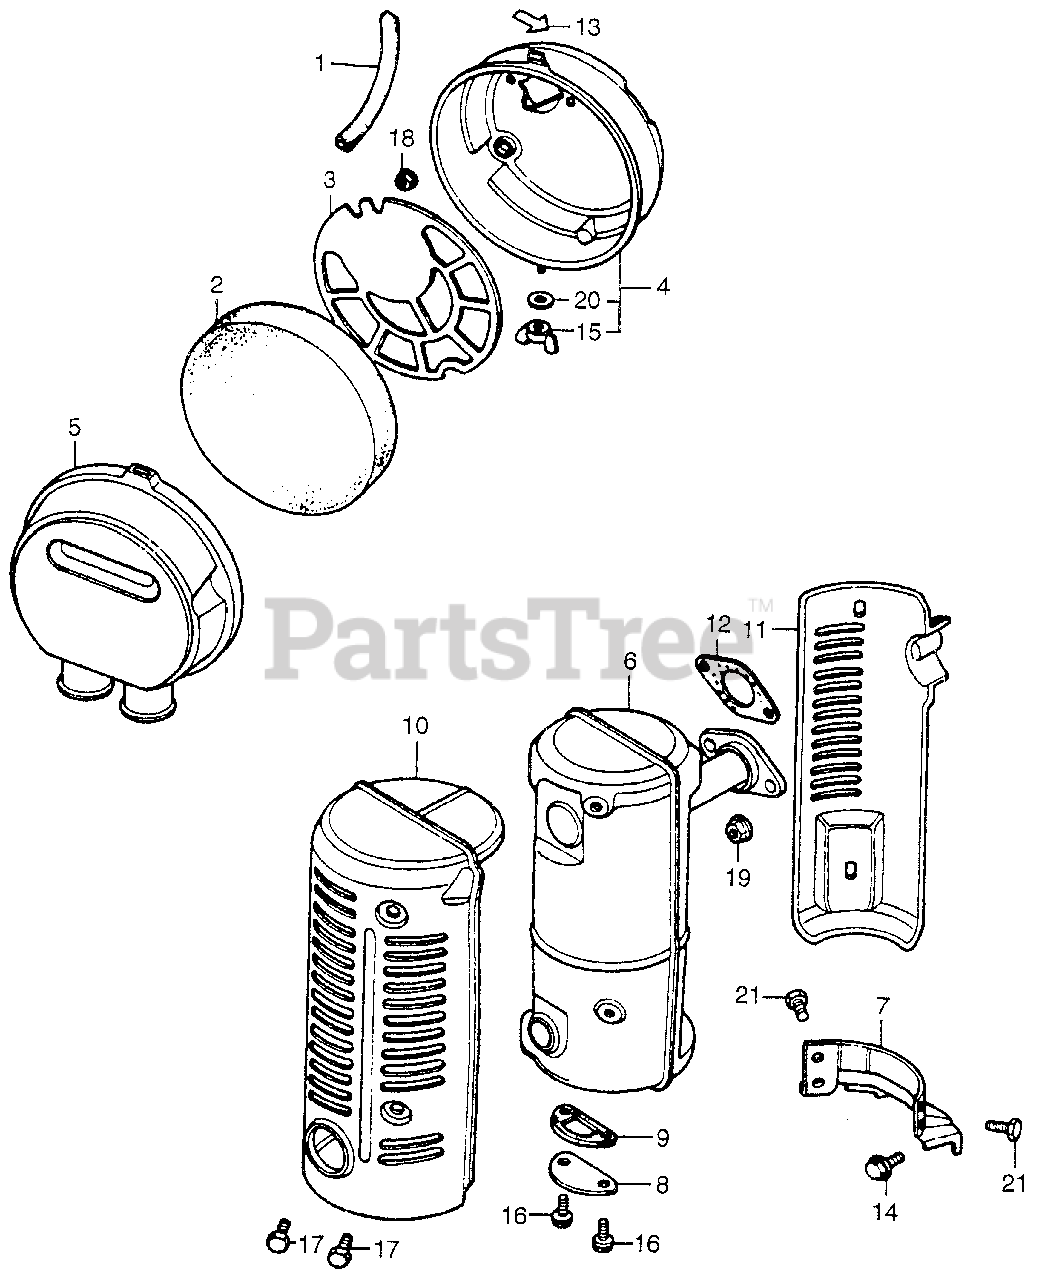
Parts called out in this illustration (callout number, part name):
1	TUBE, BREATHER
2	ELEMENT, AIR CLEANER
3	GRID, AIR CLEANER
4	HOUSING, AIR CLEANER
5	COVER, AIR CLEANER
6	MUFFLER ASSY.
7	STAY, MUFFLER
8	LID, MUFFLER
9	GASKET, MUFFLER LID
10	PROTECTOR A, MUFFLER
11	PROTECTOR B, MUFFLER
12	GASKET, MUFFLER
13	MARK, CHOKE
14	BOLT, FLANGE (8X16)
15	WINGNUT, TOOL BOX SETTING
16	BOLT, HEX. (6X12)
17	BOLT, HEX. (6X6)
18	NUT, FLANGE (6MM)
19	NUT, FLANGE (8MM)
20	WASHER, PLAIN (6MM)
21	BOLT, FLANGE (6X10)
